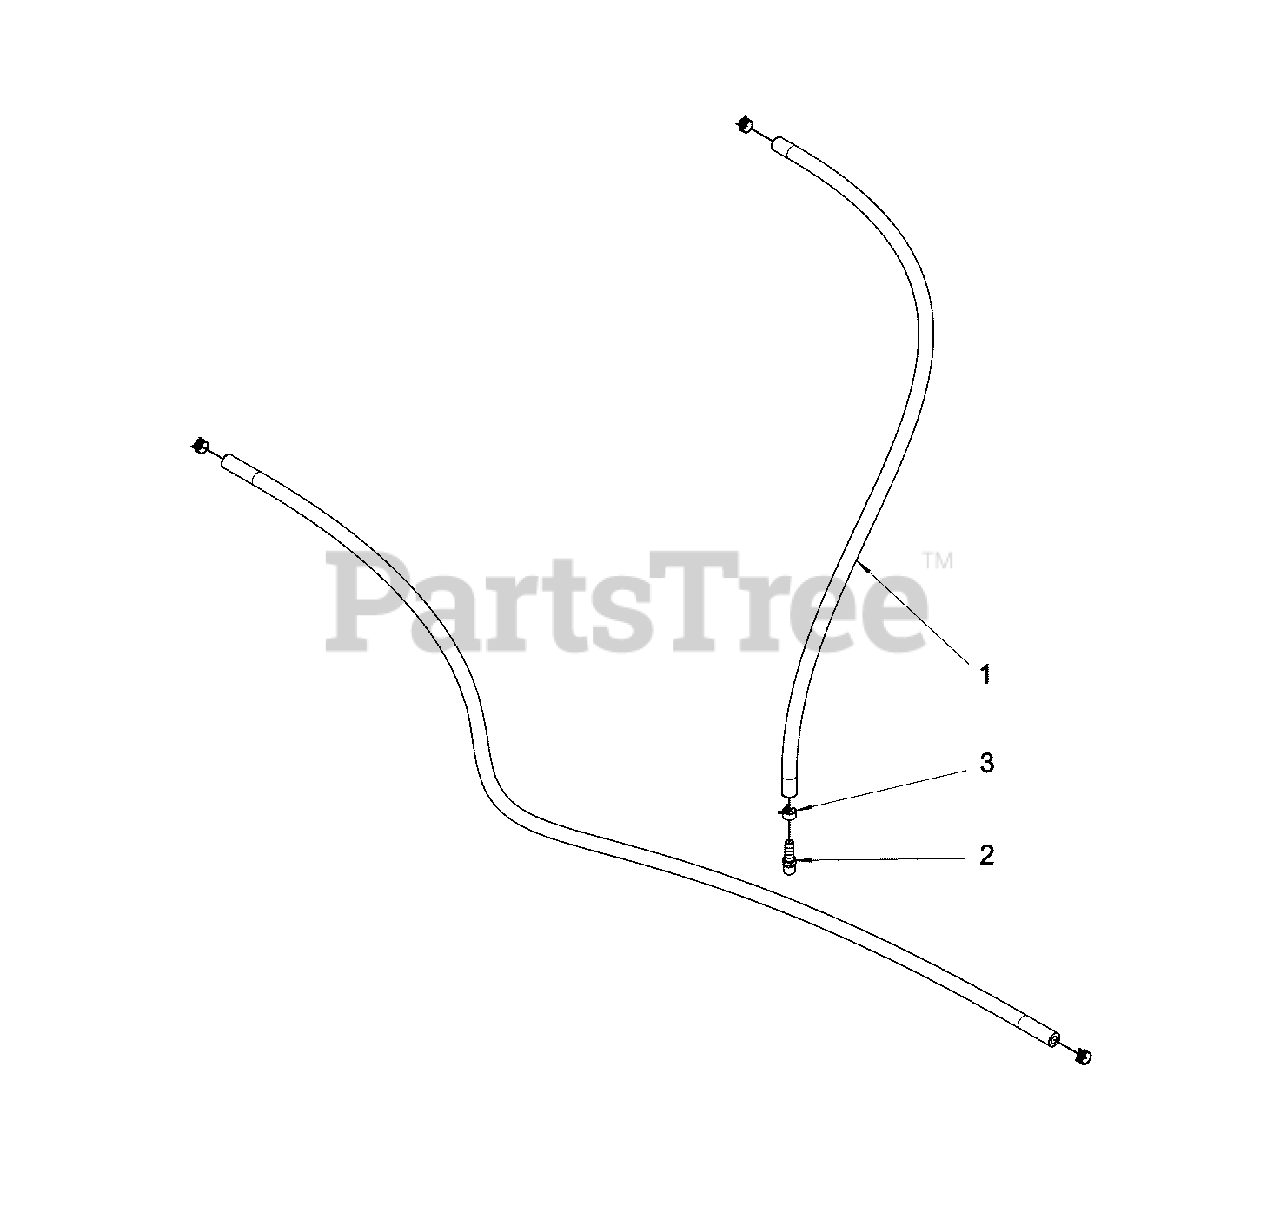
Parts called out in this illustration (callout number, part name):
1	* HEATER HOSE - 65 INCHES
2	* FITTING
3	CLAMP
